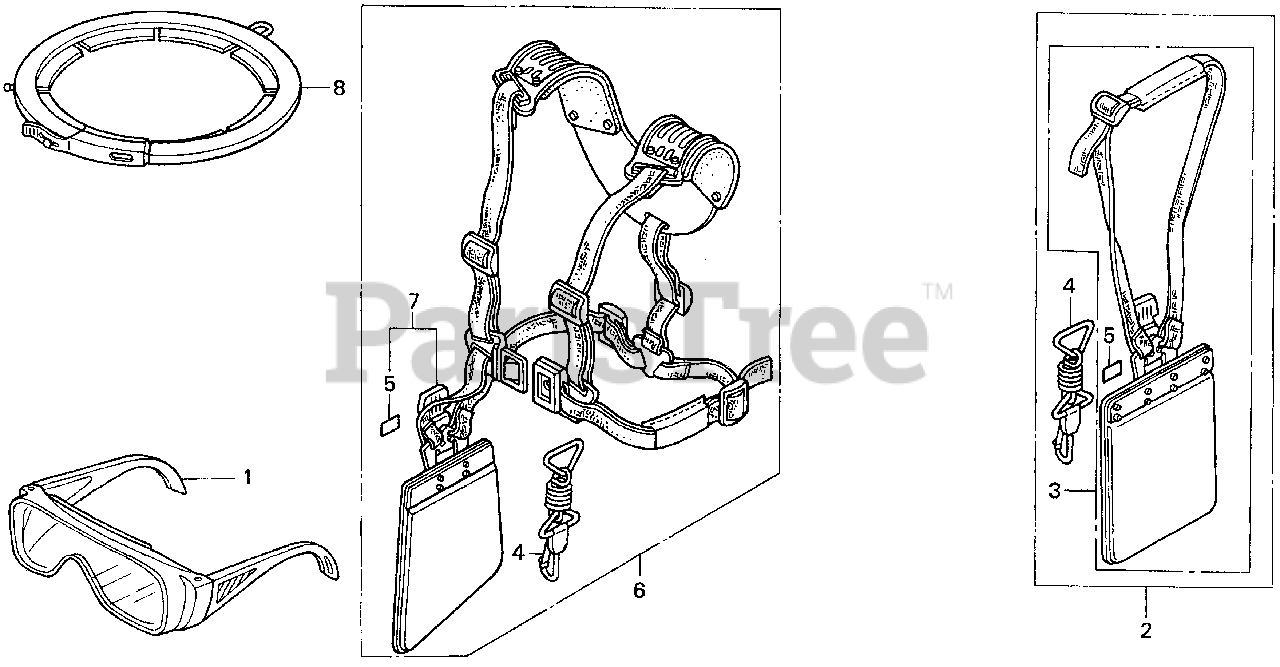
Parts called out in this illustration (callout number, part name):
1	PROTECTOR, EYE
2	BELT ASSY., SHOULDER
3	BELT, SHOULDER
4	HOOK, SHOULDER BELT
5	MARK, QUICK RELEASE (E)
